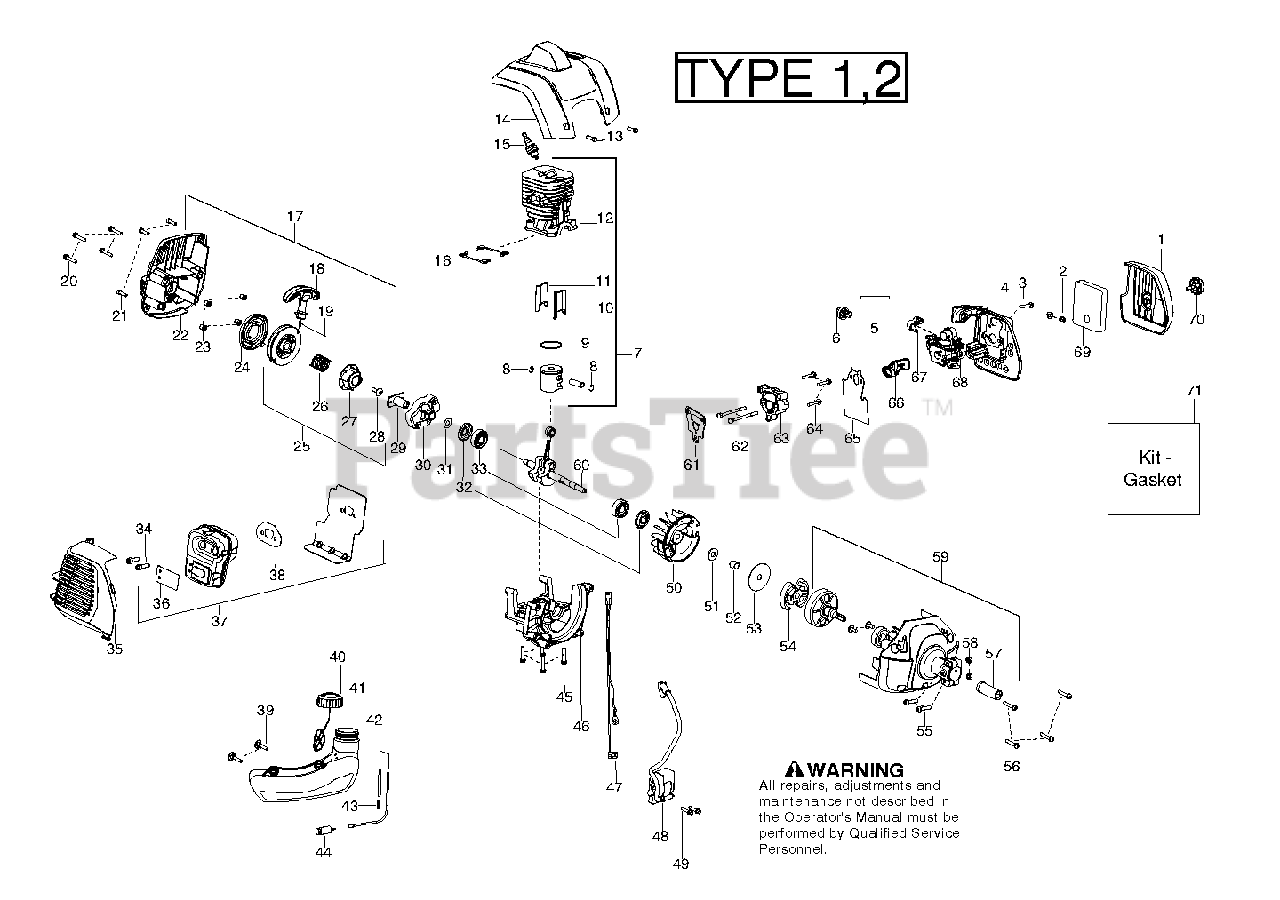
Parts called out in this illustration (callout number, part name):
4	BASE AIRBOX BLACK
7	CYLINDER ASSY
8	RETAINER PISTON PIN
13	SCREW M4 X 1.75 PT 16MM
14	CYLINDER COVER
15	PLUG-SPARK (RCJ-6Y)
16	GASKET KIT 33CC
17	STARTER ASSY
18	STARTER HANDLE
20	B0LT, C/SHAFT 36/41
21	SCREW M4 X 1.75 PT 16MM
22	STARTER HOUSING
24	SPRING STARTER
25	KIT STARTER PULLEY
29	SLEEVE COUPLING
30	STARTER CUP ASSY
32	GASKET KIT 33CC
33	BEARING RADIAL BALL (6201)
35	MUFFLER COVER
36	SPARK ARRESTER
37	MUFFLER ASSY
38	GASKET KIT 33CC
39	SCREW FUEL TANK RETAINER
40	ASSY FUEL CAP W/RETAINER
41	ASSY FUEL TANK W/RETAINER
42	KIT-LINE(FUEL)
43	FUEL LINE FITTING
44	FUEL PICK-UP ASSY
45	B0LT, C/SHAFT 36/41
48	IGNITION MODULE
50	FLYWHEEL ASSY
51	WASHER CLUTCH
52	SPACER FLYWHEEL
53	WASHER-CLUTCH
54	CLUTCH ASSY
55	SCREW-10-24 X 1" (UNC)
56	B0LT, C/SHAFT 36/41
57	GUIDE CLUTCH DRUM/FLEXSHAFT
58	LOCKNUT-HEX 10-24
59	CLUTCH COVER ASSY
60	CRANKSHAFT
61	GASKET KIT 33CC
63	ADAPTER, CARBURETOR
65	GASKET KIT 33CC
66	CARB BOOT ADAPTER
67	Choke Control Lever
68	CARBURETOR
70	AIRBOX KNOB ASSY BLACK
71	GASKET KIT 33CC
